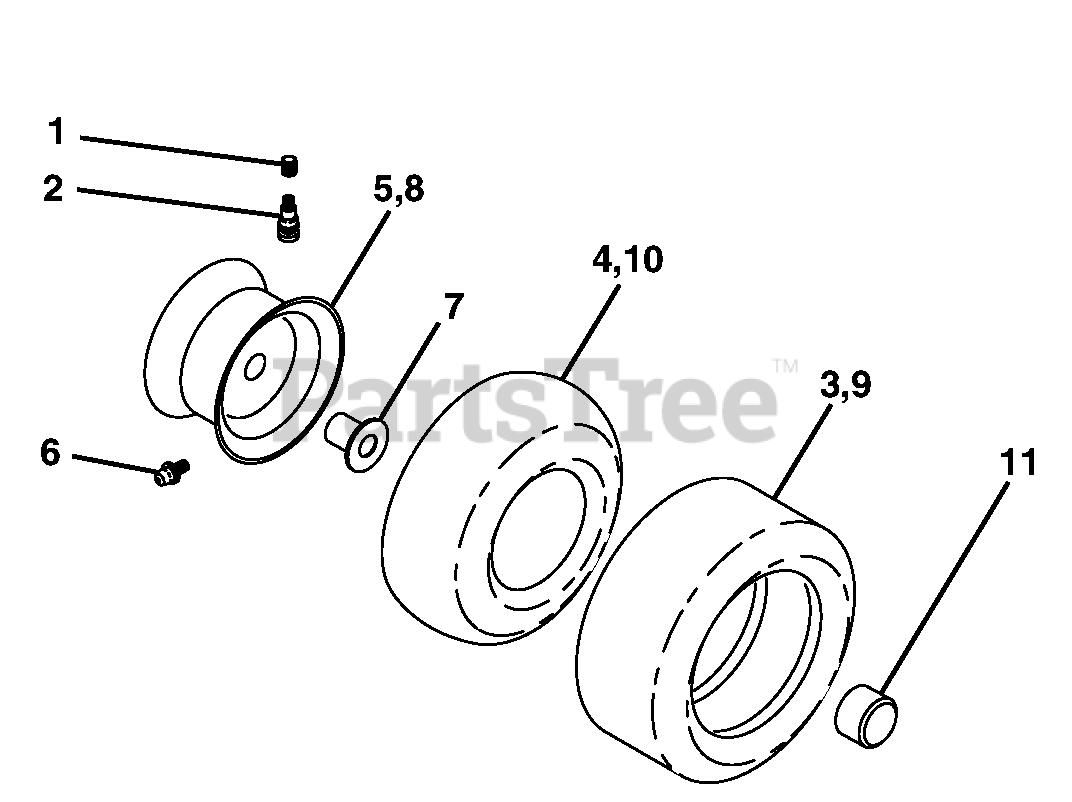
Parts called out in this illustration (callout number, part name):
1	Cap, Tire valve
2	Stem, Valve
4	Tube, Front (Service item only)
5	Rim assembly, 6"front
6	Fitting, Grease (Front wheel only)
7	Bearing, Flange (Front wheel only)
8	Rim assembly, 8" rear
9	Tire, Rear
10	Tube, Rear (Service item only)
11	Cap, Hub Axle
